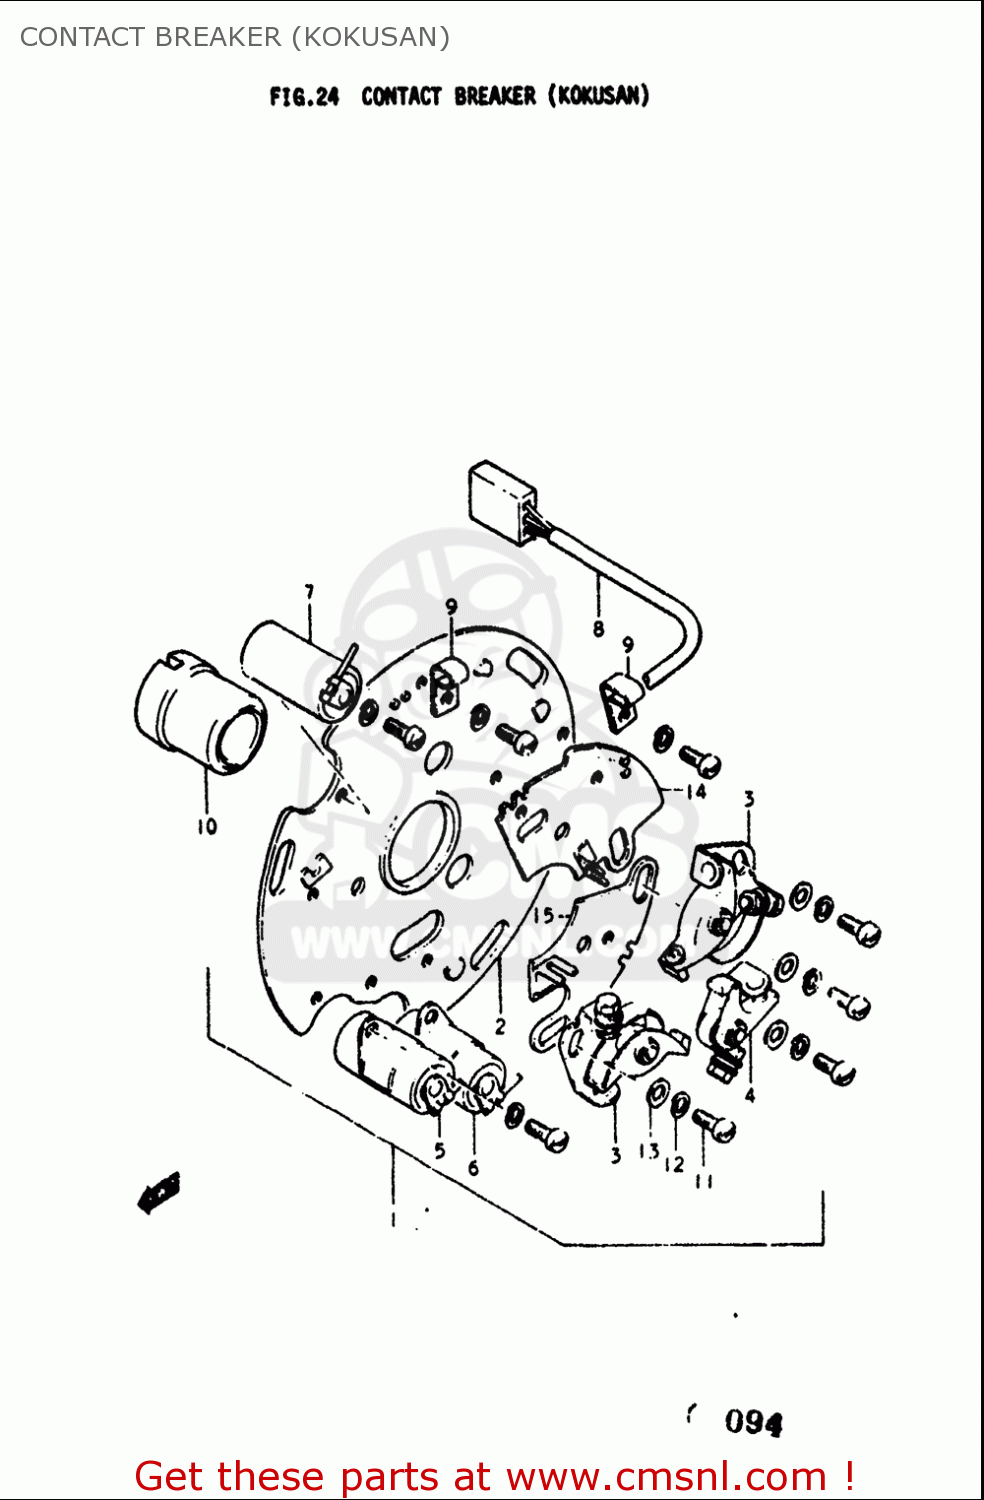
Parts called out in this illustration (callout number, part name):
3	POINT ASSY,CONTACT
4	POINT,CTR
7	CONDENSER,R
11	SCREW 4X6
12	WASHER,LOCK
13	WASHER
